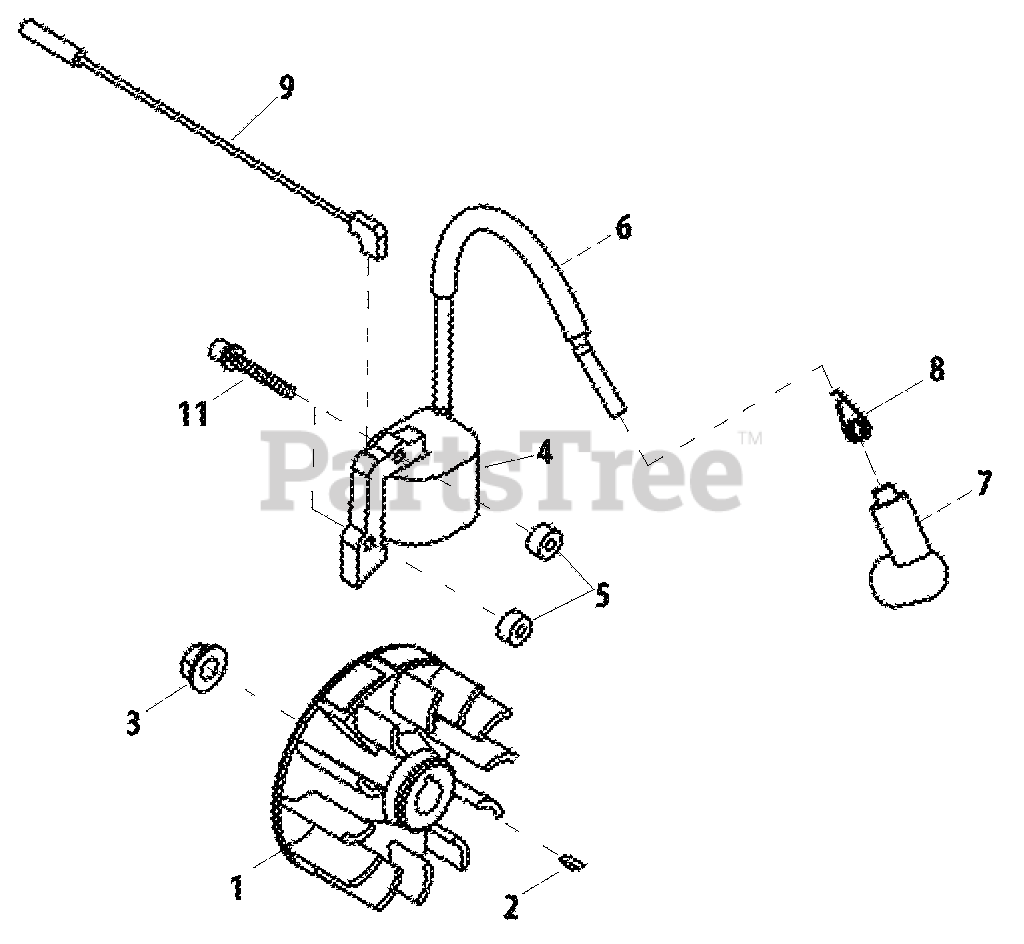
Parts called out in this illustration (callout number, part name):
1	FLYWHEEL
2	KEY - 3X10
3	NUT - 8
4	COIL, IGNITION
5	INSULATOR
6	TUBE
7	CAP, SPARK PLUG
8	TERMINAL, SPARK PLUG CAP
9	LEAD - GROUND
11	SCREW - 4X26
